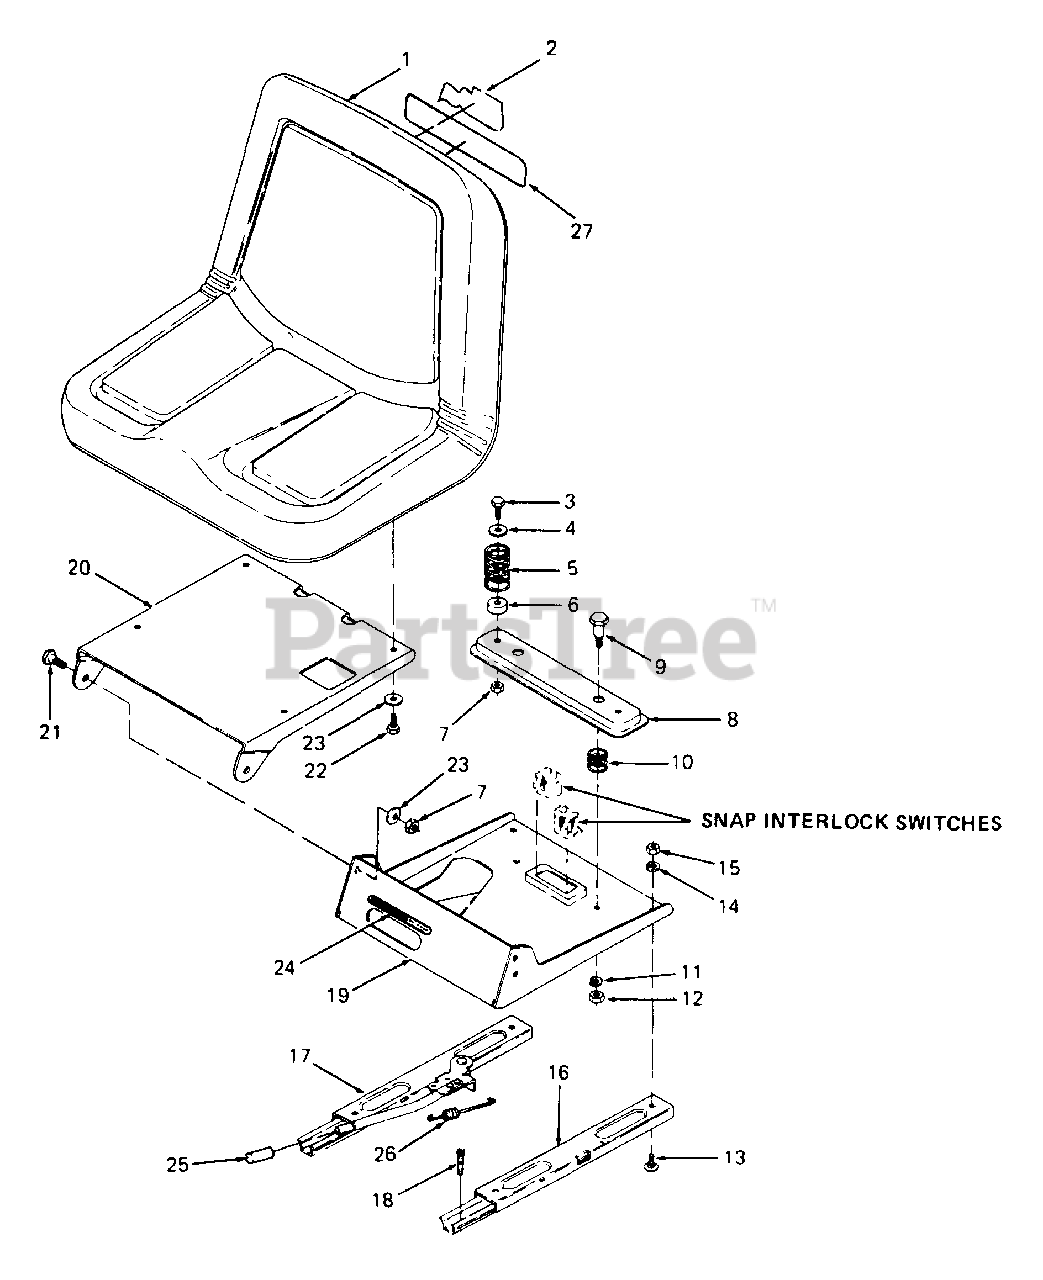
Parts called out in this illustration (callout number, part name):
1	Seat
2	Graphic, Made in USA
3	Screw, Hex Cap, 5/16-18 x .88 Lg GR5
4	Washer, Flat, .344 x .875 x .06 Thk
5	Spring, Comp, 1.28 OD x 2.18 Lg
6	Bushing, .930 OD x .50 Lg
7	Nut, Hex Center Lock, 5/16-18 GR5
10	Spring, Comp, 1.00 OD x .86 Lg
11	Washer, Lock, 3/8
12	Nut, Hex, 3/8-16 GR5
13	Bolt, Sht Nk Carriage, 5/16-18 x .62 Lg
14	Washer, Lock, 5/16
15	Nut, Hex, 5/16-18 GR5
16	Slide, Seat - LH
17	Adjuster, Manual Seat - RH
18	Screw, Socket Hd Cap, 5/16-18 x 1.00 Lg
22	Screw, Hex Cap, 5/16-18 x .75 Lg GR5
23	Washer, Bell, .345 x .88 x .060 Thk
24	Label, Seat Adjustment
25	Cover, Handle
27	Graphic, Seat Back Script
